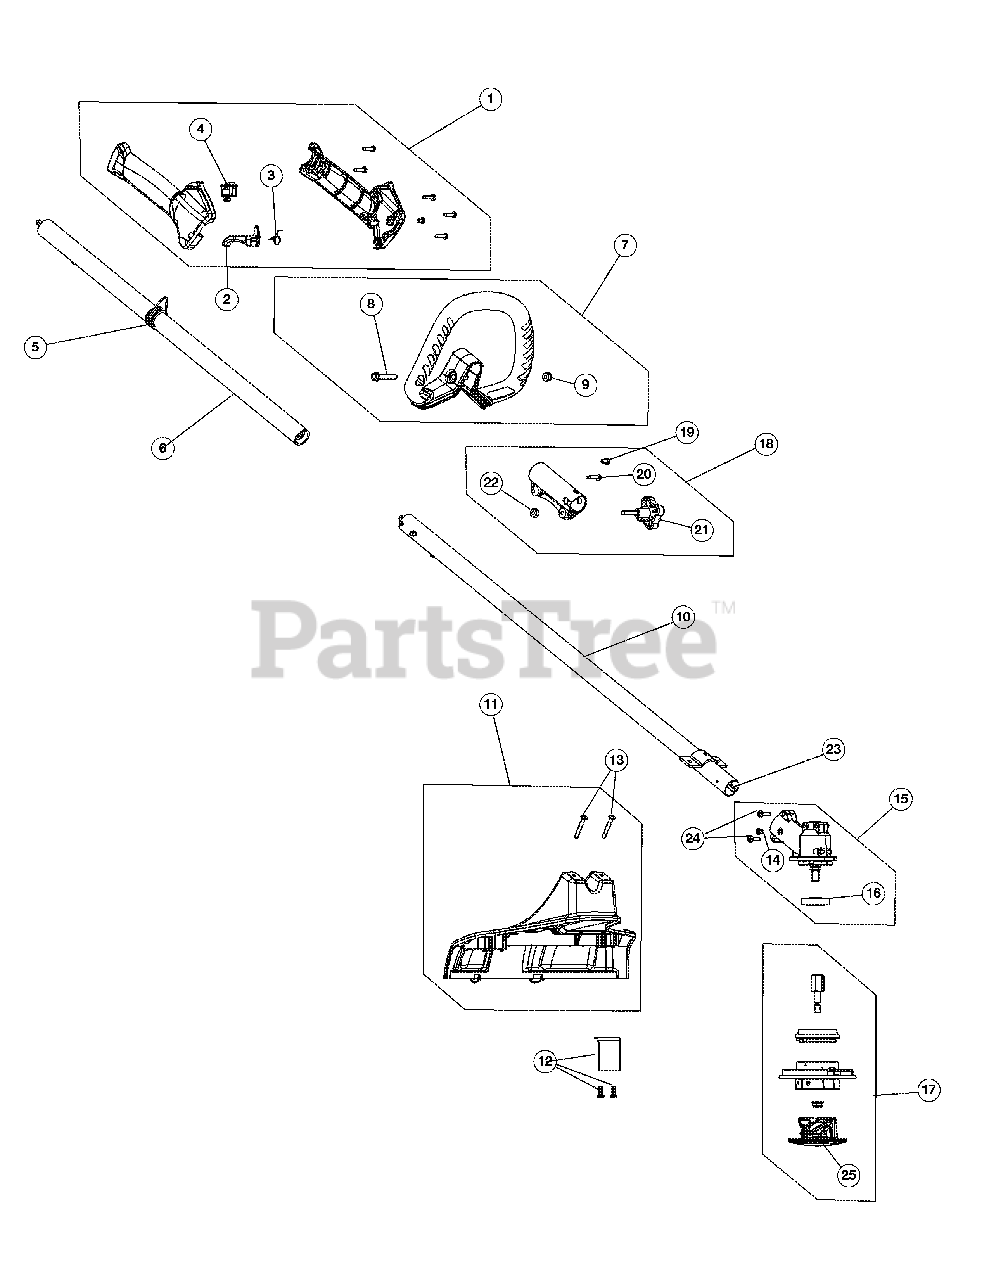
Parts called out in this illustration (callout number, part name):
1	Throttle Housing Assembly (Incl. Ref No. 2-4)
2	Throttle Trigger
5	Shoulder Strap Clip
6	Upper Drive Shaft Housing Assembly
7	D-Handle Assembly (Incl. Ref No. 8 & 9)
9	Nut
10	Lower Drive Shaft Housing Assembly
11	Shield Assembly (Incl. Ref No. 13)
12	Blade Assembly
14	Anti-Rotation Screw
15	Gear Box (Incl. Ref No. 14, 16 & 24)
16	Gear Box Spacer
17	Cutting Head Assembly (Incl. Ref No. 25)
18	Split Boom Coupler (Incl. Ref No. 19-22)
21	Adjustment Knob
22	Knob Retaining Nut
23	Lower Flexible Drive Shaft
24	Gear Box Screw
25	Cutting Head Cap
